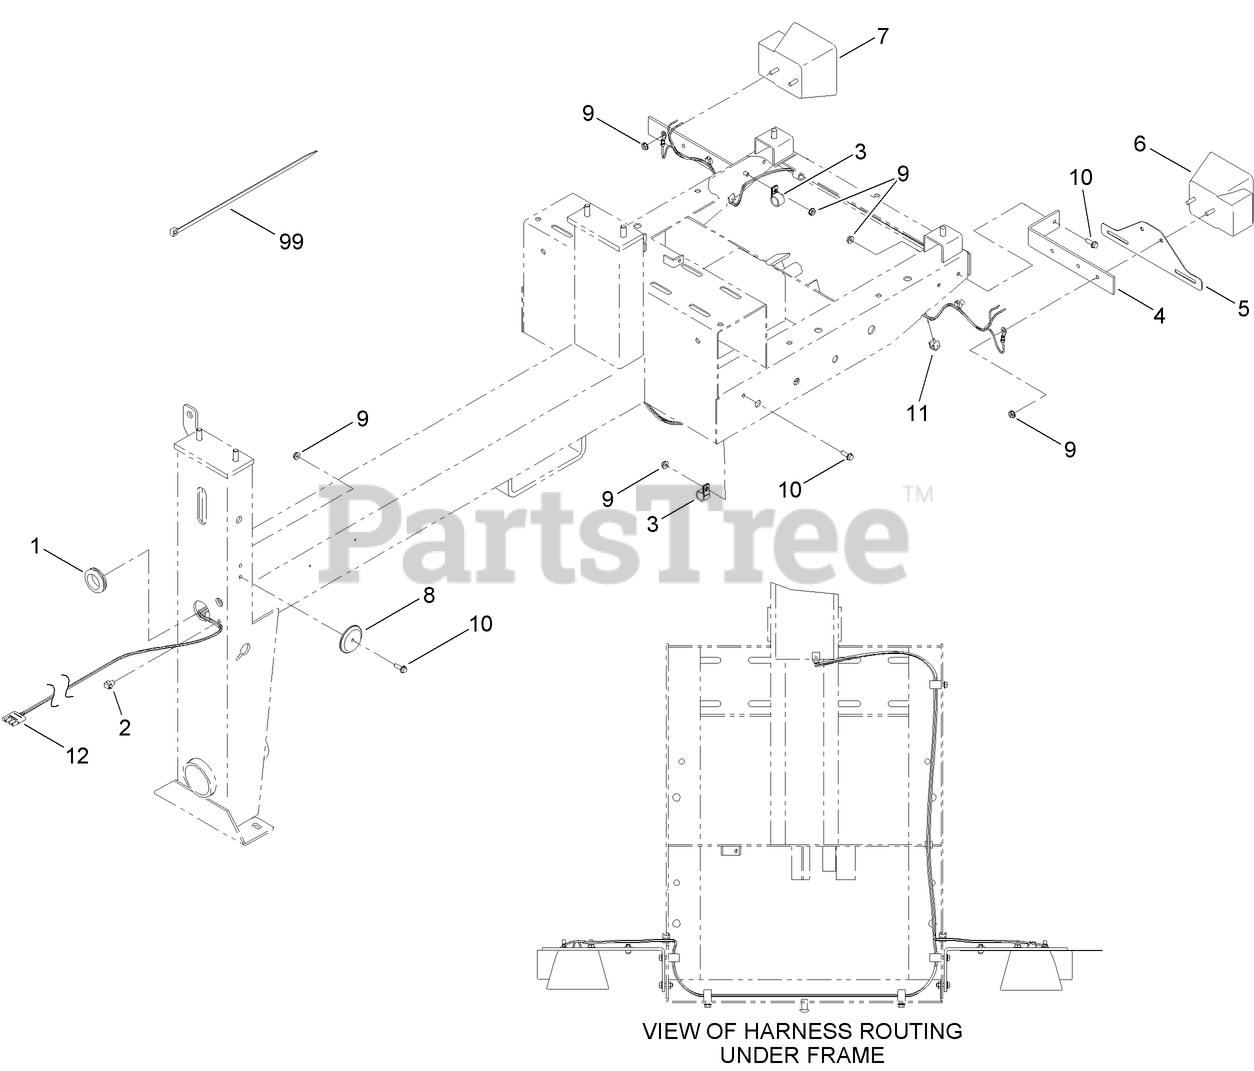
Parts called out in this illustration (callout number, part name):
1	GROMMET
2	CLIP-TIE
3	CLAMP-CABLE
4	BRACKET-UNIVERSAL
5	HOLDER-PLATE, LICENSE
6	LIGHT-TAIL, LH
7	LIGHT-TAIL, RH
8	Reflector-Amber
9	NUT-KEPS
10	SCREW-HHF
11	CLIP-EDGE
12	HARNESS-WIRE, TRAILER LIGHTS
99	TIE-CABLE
